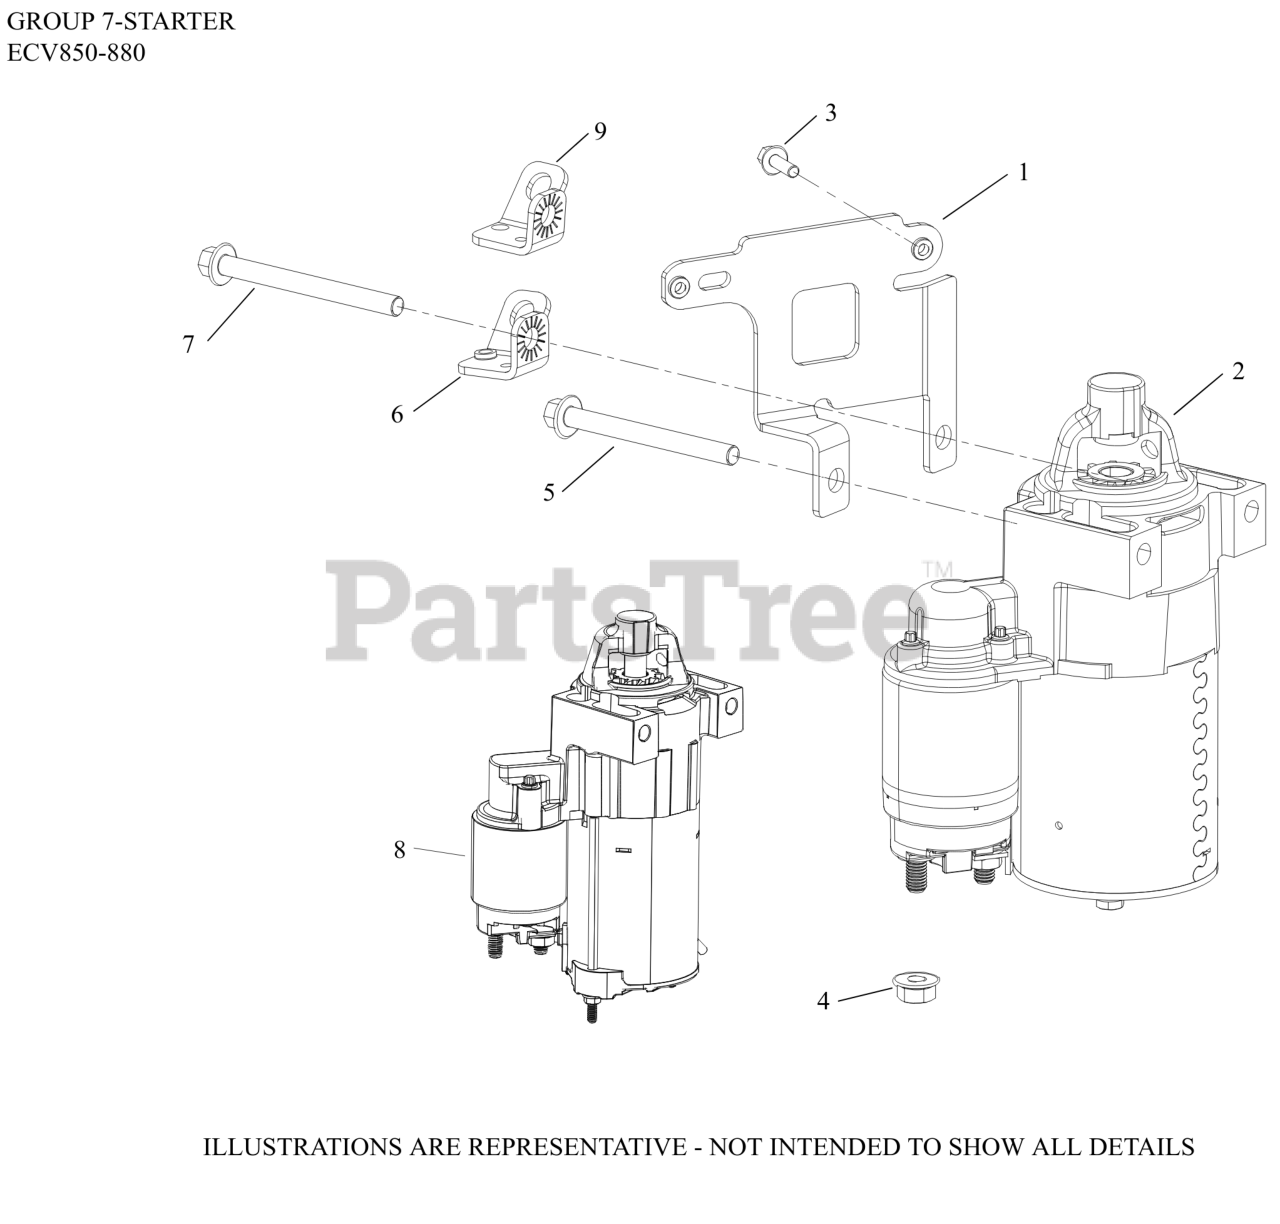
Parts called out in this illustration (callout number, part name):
1	BRACKET, ECU
2	STARTER, SOLENOID SHIFT-(#2509824S)
3	SCREW, HVY FLG M5X.8X16
4	NUT, FLG M8X1.25
5	SCREW, FLG M8X1.25X80
